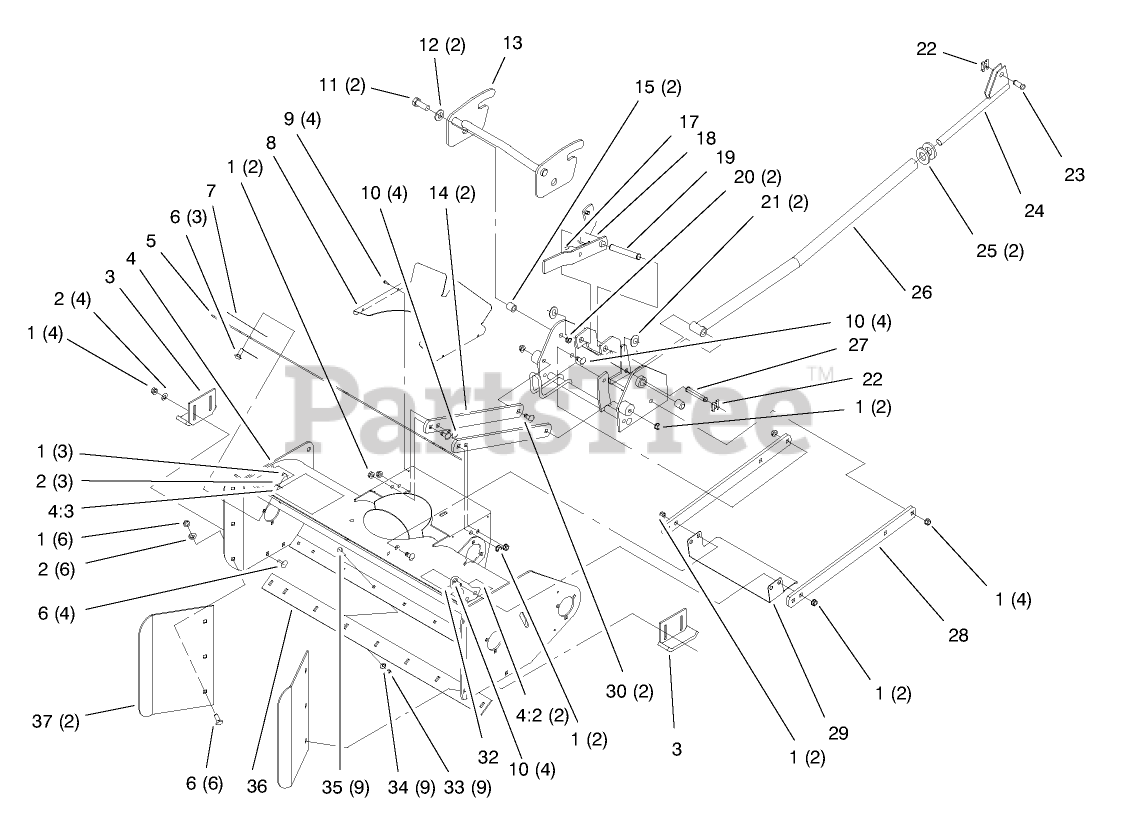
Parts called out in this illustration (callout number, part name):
1	NUT-LOCK, NI
2	WASHER-FLAT
4:2	DECAL-DANGER
4:3	DECAL-WARNING
5	PLATE-EXTENSION
6	BOLT-CARR
9	SCREW-TAPTITE
10	Bolt
11	SCREW-HH
12	WASHER-FLAT
15	BUSHING-PIVOT
16	WASHER-FLAT
17	FITTING-GREASE
20	NUT-LOCK, NI
21	RING-RETAINING
22	CLIP-PIN
23	PIN-CLEVIS
25	WASHER-FLAT
27	PIN-CLEVIS
30	SCREW-CARR
33	NUT-LOCK, NI
34	WASHER-FLAT
37	PLATE-EXTENSION, RH
